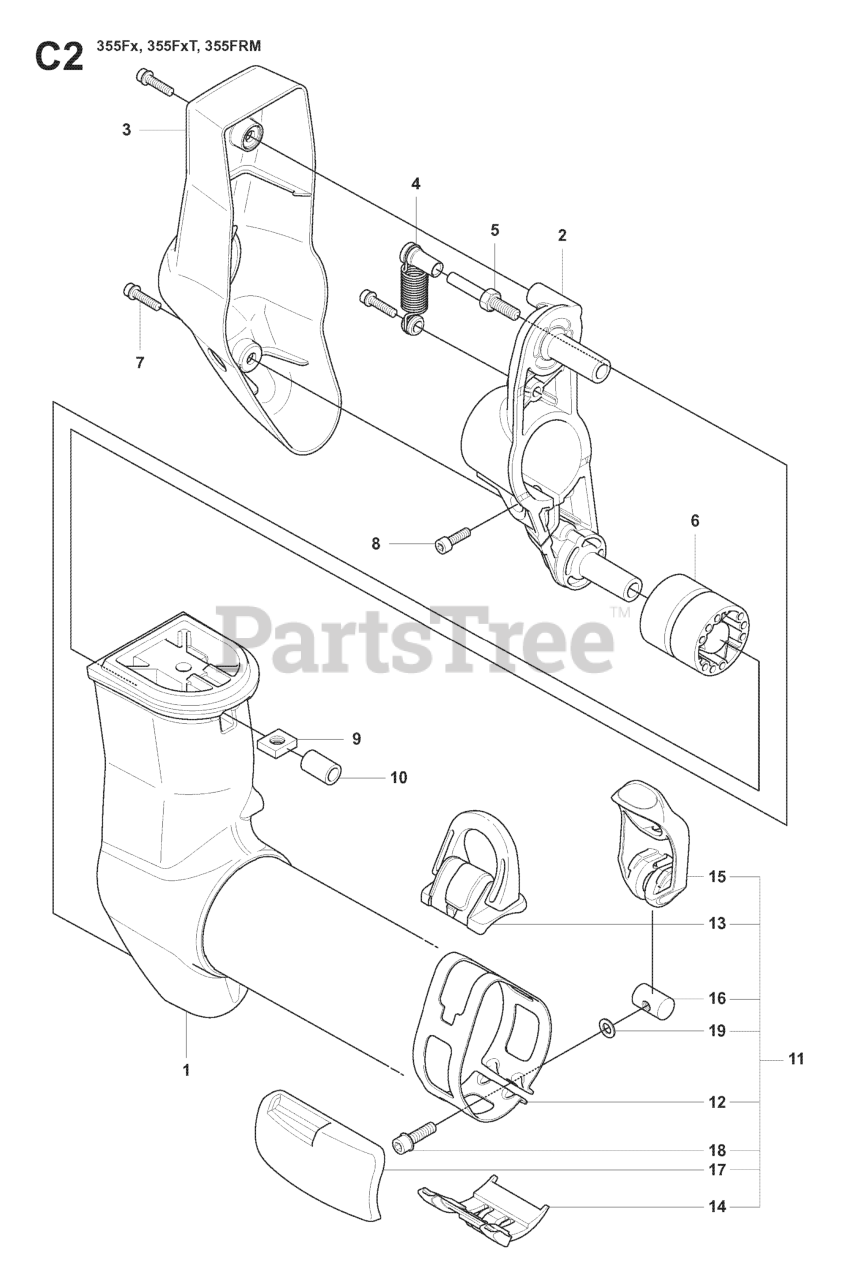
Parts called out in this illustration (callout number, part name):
1	SUSPENSION
4	SPRING
5	PARALLEL PIN
6	ANTIVIBE ELEMENT
7	SCREW IHSCFM
14	GUIDE RAIL
17	WEAR PROTECTION
19	WASHER 5.3X12
